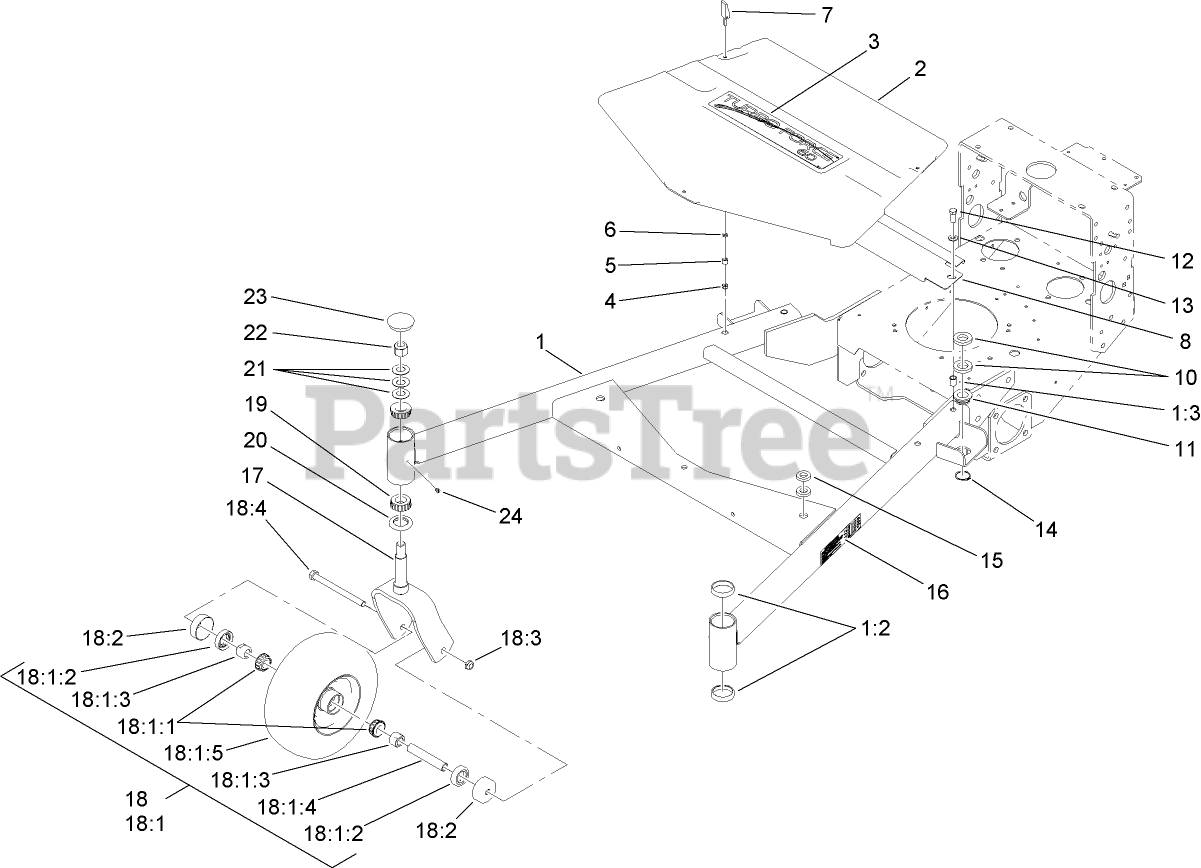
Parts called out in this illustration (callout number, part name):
1	CARRIER FRAME ASM
1:2	CUP-BEARING
1:3	INSERT-NUT
2	COVER-CARRIER FRAME
4	NUT-LOCK, HH
5	BUSHING-LATCH, SWELL
6	WASHER
7	HANDLE-LATCH, SWELL
8	SHIELD-BELT
10	SPACER-SUPPORT, DECK
11	BUSHING-DECK
12	SCREW-HH
13	WASHER-FLAT
14	RING-RETAINING
15	SPACER
16	DECAL-HOC
17	WLD, CASTER FORK
18	WHEEL/TIRE AND BEARING ASM
18:1	WHEEL AND BEARING ASM
18:1:1	BEARING-CONE, TAPER
18:1:2	SEAL-CASTER
18:1:3	SPACER-NUT
18:1:4	AXLE-CASTER
18:1:5	WHEEL AND TIRE ASM
18:2	GUARD-SEAL
18:3	NUT-LOCK, NI
18:4	SCREW-HH
19	BEARING-ROLLER, TAPERED
20	SEAL-GREASE
21	WASHER-BELLVILLE
22	NUT-LOCK, NI
23	CAP-GREASE
